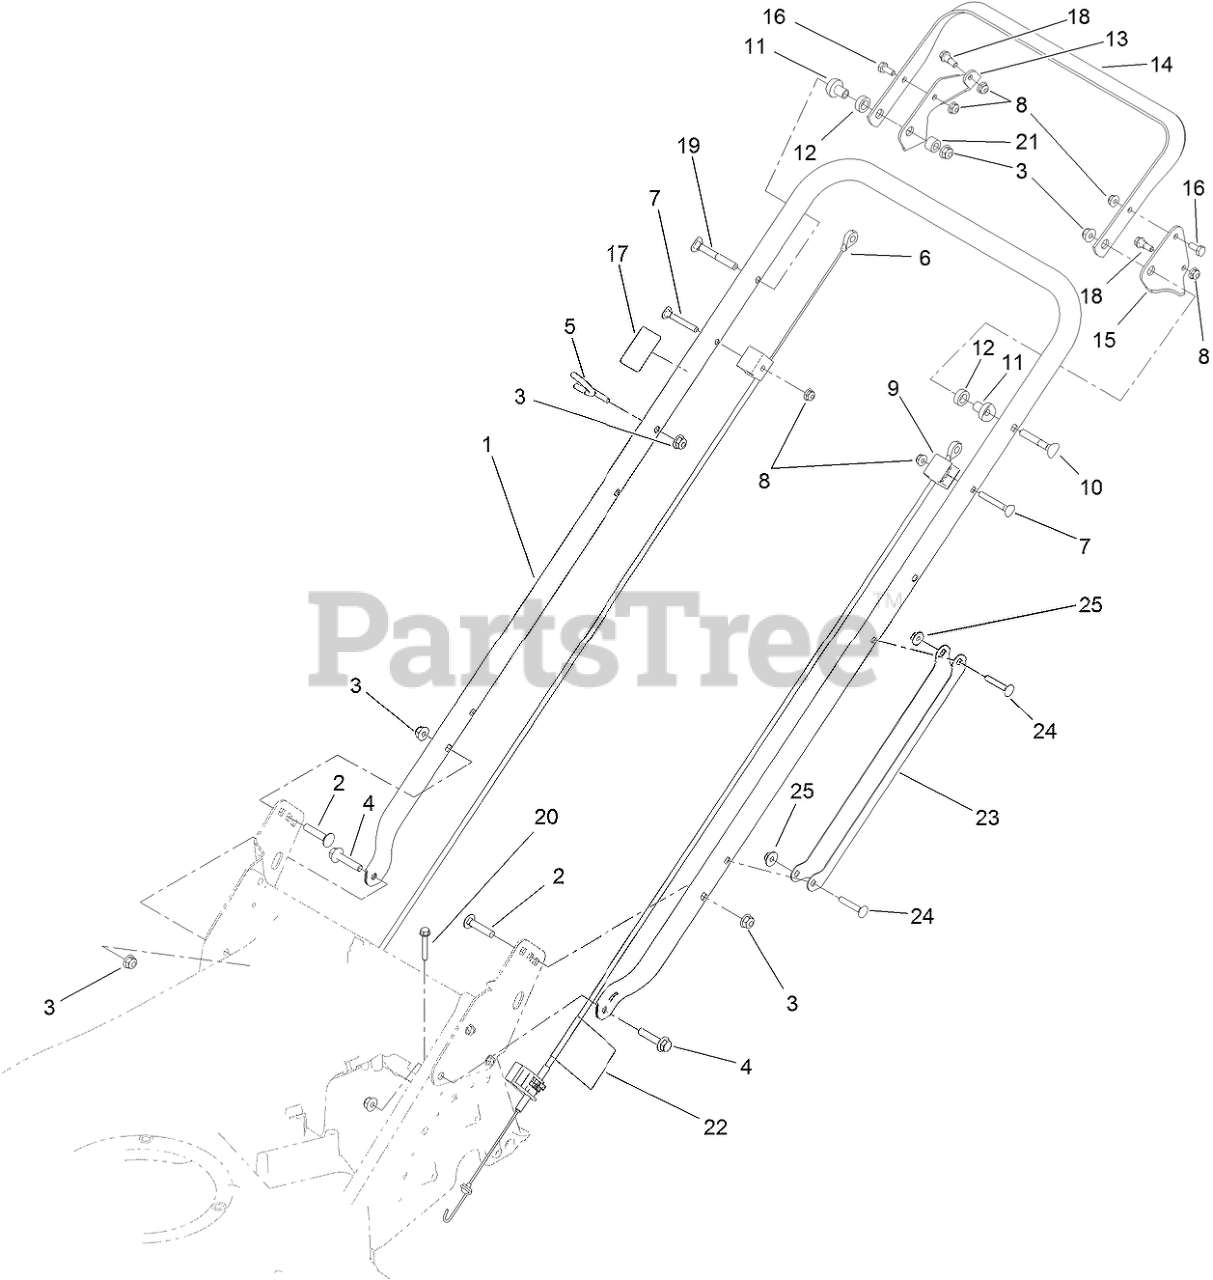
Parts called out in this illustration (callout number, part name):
1	HANDLE
2	BOLT-CARR
3	NUT-HF, NI
4	SCREW-HHF
5	GUIDE,ROPE
6	CABLE-BRAKE
7	SCREW
8	NUT-HF
9	CABLE-TRACTION
10	SCREW-HANDLE
11	SPACER-SUPPORT
12	SPACER-NYLON
13	BRACKET-CONTROL, BRAKE
14	BAR-CONTROL, ZONE START
15	LEVER-CONTROL, TRACTION
16	SCREW-HH
17	DECAL-PRIMER
18	BOLT-SHOULDER
19	SCREW-HANDLE
20	SCREW-HWH
21	SPACER
22	DECAL-ADJUST, SELF PROPEL DRIVE
23	GUARD-CABLE, HANDLE
24	SCREW-CARR
25	NUT-HEX FLG
